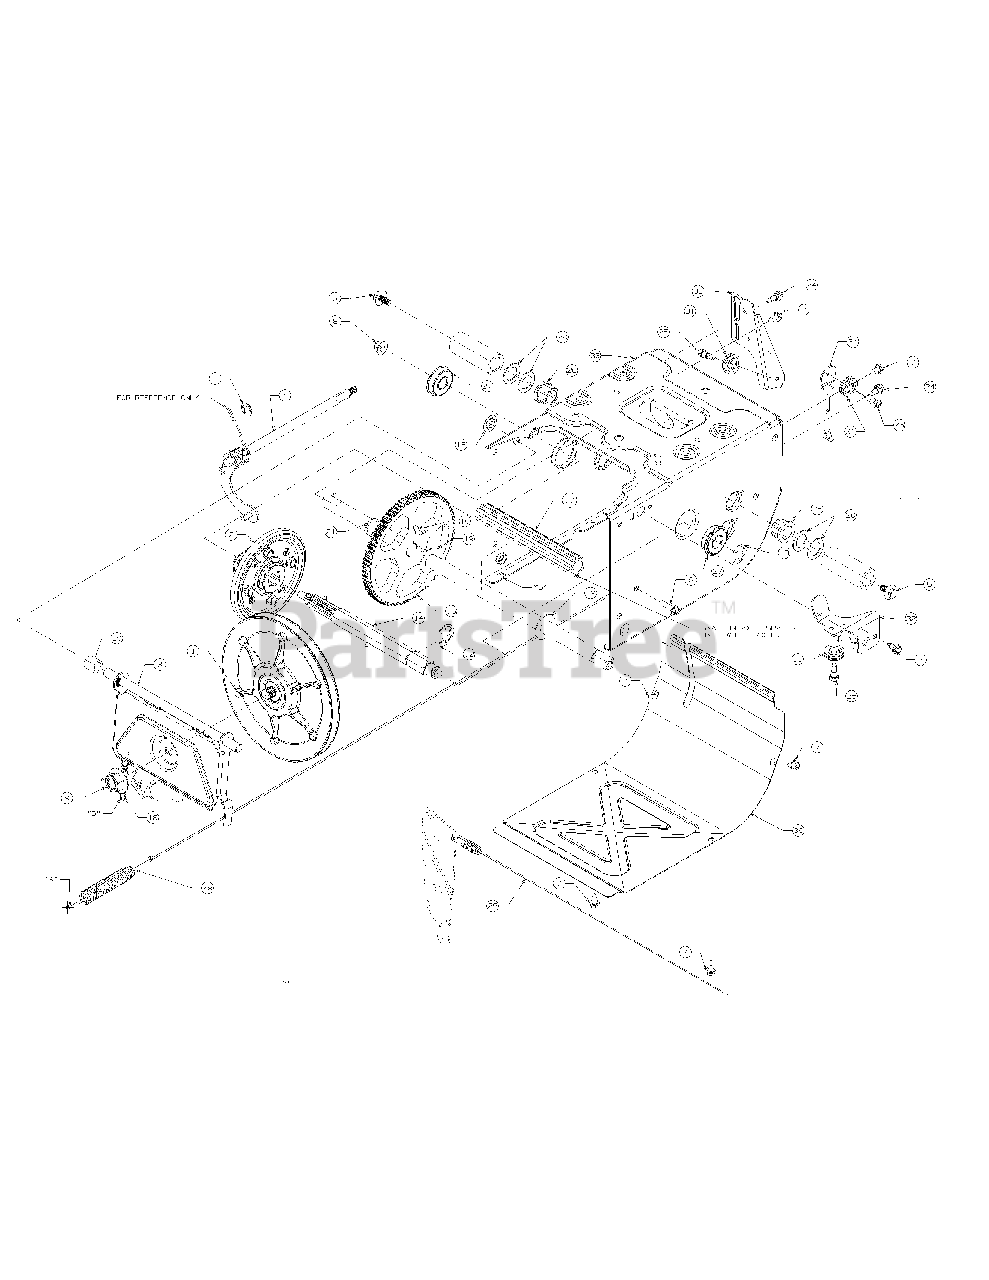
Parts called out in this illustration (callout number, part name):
1	Disc Assy-Friction
2	Friction Wheel Asm
3	Bracket Assy-Support
4	Shift Asm-Rod S/T
5	Hhcs-5/16-24 X .75
6	Screw-Tap 1/4-20
7	Screw Hex.Wash.Hd
8	Nut-Flange Lk.Nylon
9	Nut-Hex Flange 5/8
10	Key 3/16 X 3/4 H
11	Ring-E For .500
12	Ring-Retaining-E T
13	Ring-E
14	Shaft-Hex .812
15	Gear:80 Tooth
16	Cap-Push
17	Spacer-Axle 7.40"
18	Spring-Extension
19	Washer-Fl-.760Id X
20	Washer-Fl .793 I
21	Washer-Flat .75X1
22	Grease
23	Grease
24	Screw:Shoulder
25	Screw-1/4-28 X .32
26	Flange Bearing
27	Ball Bearing
28	Cable: Clutch
29	Cable-Drive Whe
30	Spacer-.513 Id X .
31	Roller-Cable Guide
32	Bracket-Auger Cable
33	Frame-Whl Drv 600
34	Bracket:G
35	Bracket-Guide Clutch
36	Cover-Frame Snowth
